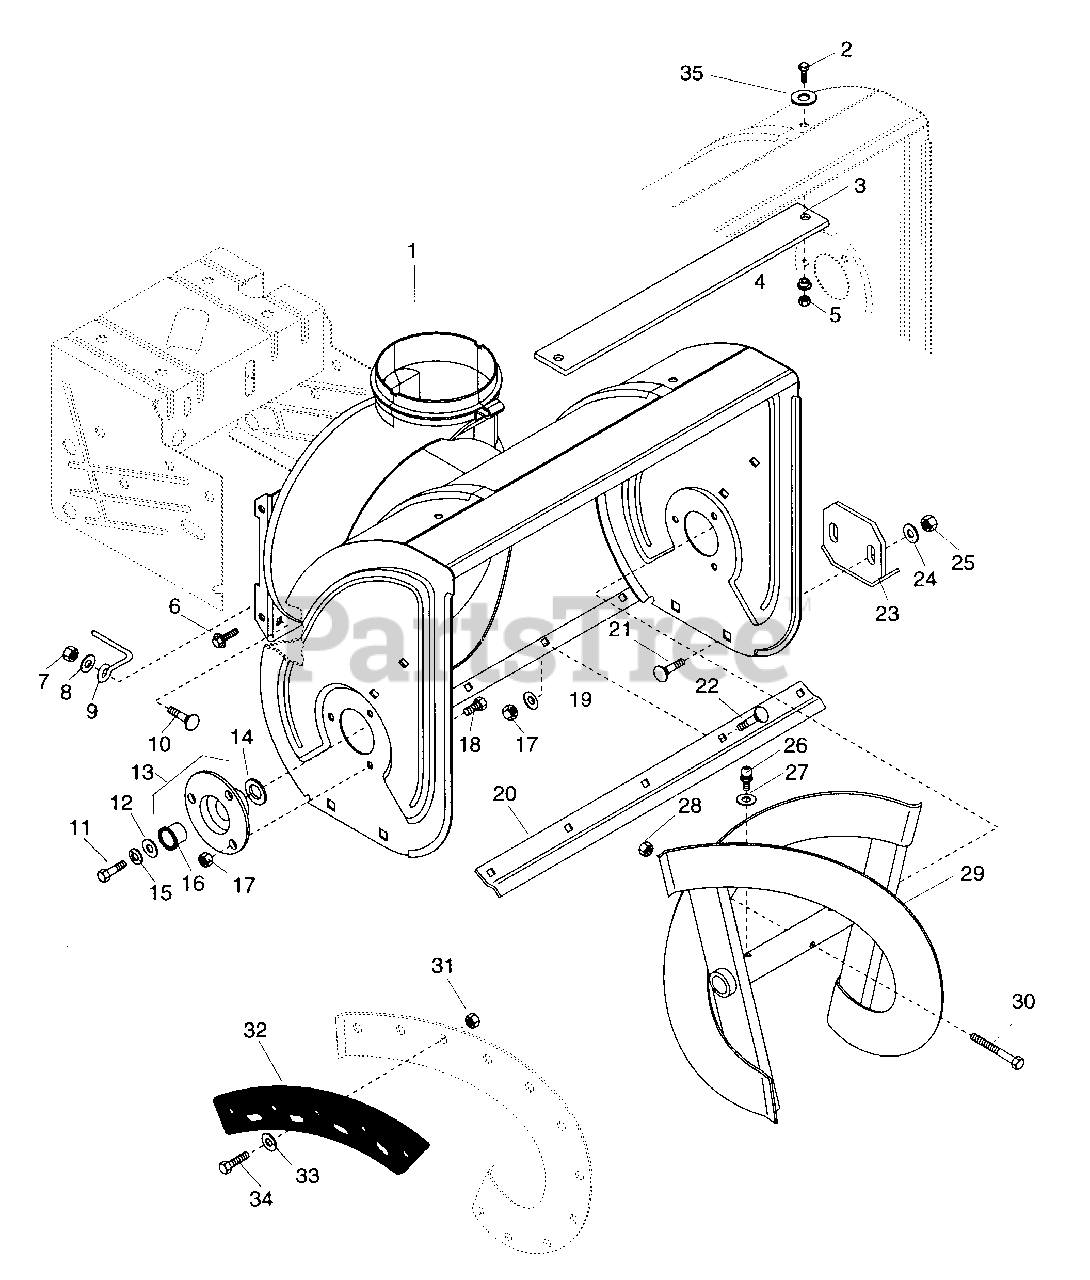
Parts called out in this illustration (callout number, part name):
1	AUGER/IMPELLER HOUSING 20" ST2
1	AUGER/IMPELLER HOUSING 24"
2	BLT-HEX .31-18X1.25 PL GR5
3	WEIGHT-AUGER/IMPELLER HSG
4	BSHG-FLG .325X.500X.70X.875
5	NUT-LK .312-18 GR A PL
6	SCR-TAP .312-18X.50 HWH PL TR
7	NUT-LK-NYL.312-18 PL
8	WSHR-FL-STL .328X.875X.062 PL
9	BELT FINGER
10	BLT-RDHDSQNK.31-18X.75GR5SHTPL
11	BLT-HEX .31-18X.63 PL GR 2
12	WSHR-FL-STL .344X1.375X.075 PL
13	BEARING FLANGE ASSEMBLY
14	WSHR-FL-STL.812X1.500X.139
15	WSHR-LK .312X.097 PL HVY
16	BSHG-FLG .750X1.000X.625X1.250
17	NUT-LK-FLG .250-20 PL
18	BLT-SERNK SL .25-20X.50 PL
19	WSHR-FL-STL.281X.62X.065 PL
20	SCRAPER BLADE
21	BLT-RDHDSQNK .38-16X.75 SHT PL
22	BLT-RDHDSQNK .25-20X.50
22	BLT-RDHDSQNK .25-20X.50 SHT PL
23	RUNNER
24	WSHR-FL-STL .38X.875X.083 PL
25	NUT-LK-CTR .375-16 GR A PL
26	FTG-LUBE .25-28X.256 YWZC
27	WSHR-FL-STL .265X.500X.087 PL
28	NUT-LK-CTR .250-20 PL
29	RAKE, RIGHT-24"(.75ID X 10.88)
29	RAKE, LEFT-24(.75ID X 10.88OD)
29	RAKE, RIGHT-20(.75ID X 10.5OD)
29	RAKE, LEFT-20"(.75ID X 10.5OD)
30	SHEAR BOLT WITH NUT
31	NUT-LK TOP 10-24 PL
32	RAKE EDGE W/HARDWARE
33	WSHR-FL-STL .194X.492X.047 PL
34	SCR-MCH 10-24X.63 HEX PL
35	WSHR-FL-STL .406X1.000X.188 PL
